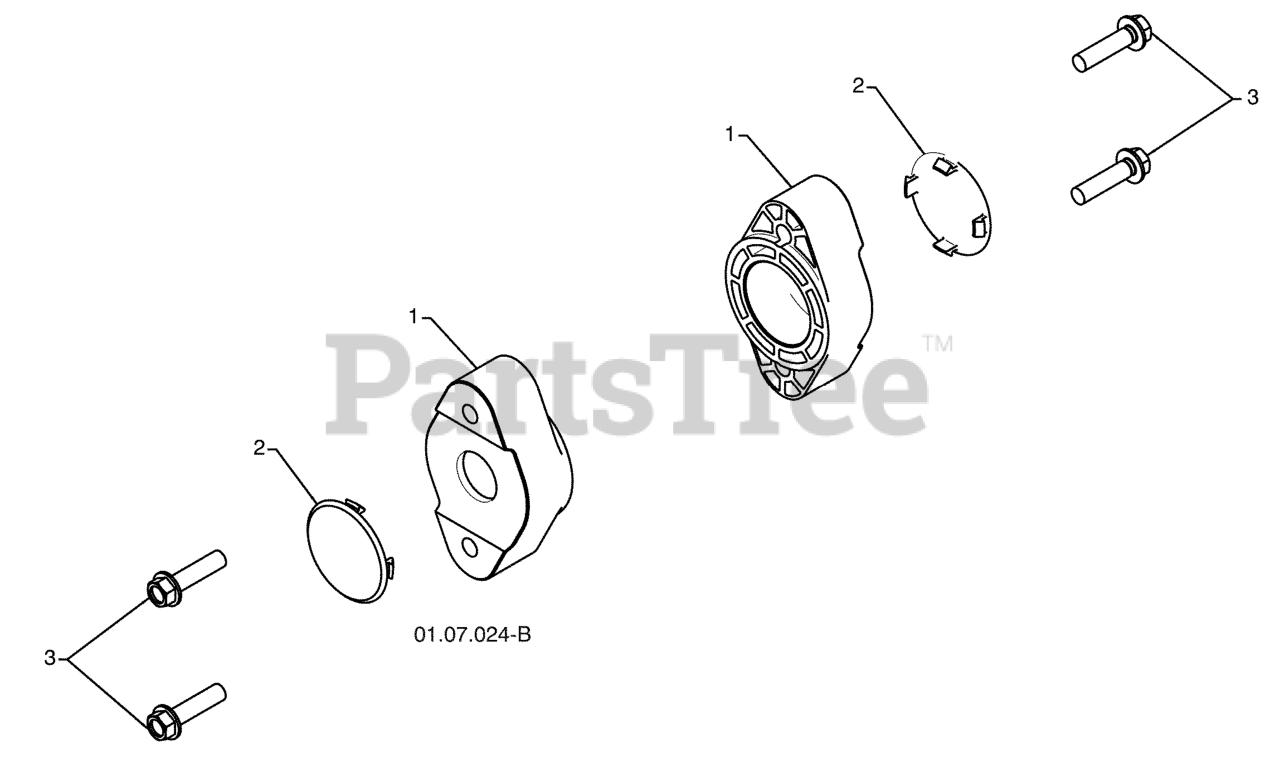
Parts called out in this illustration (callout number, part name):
1	BEARING.AUGER.SHAFT
2	PLUG.BEARING.HOLE.HSG
3	SCREW, HEX HD 5/16X1
